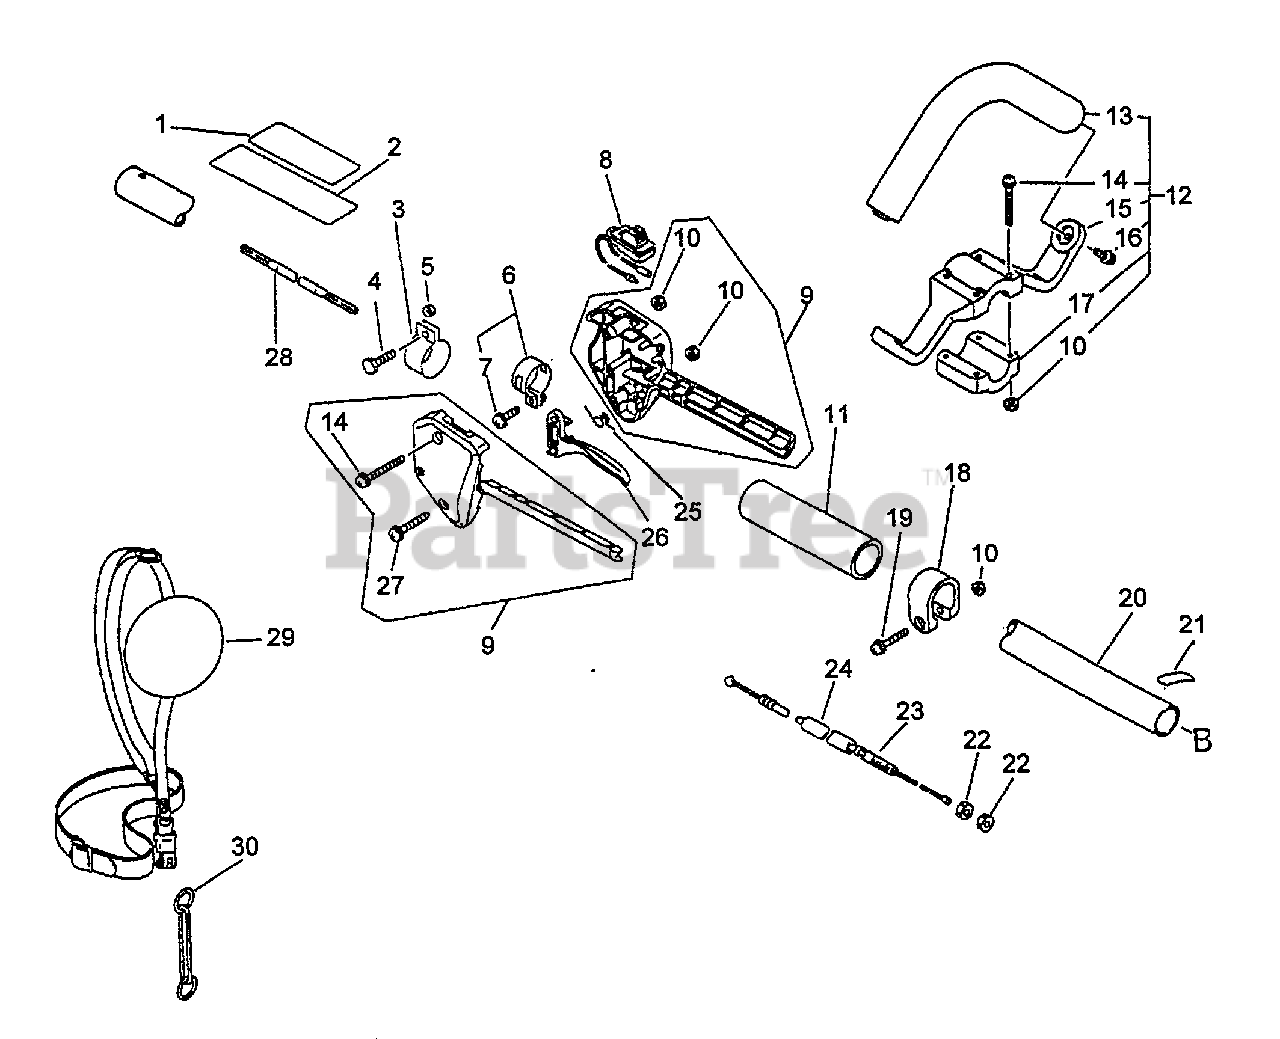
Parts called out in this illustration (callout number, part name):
1	LABEL - CAUTION
2	LABEL - CAUTION
4	BOLT - 5X18
6	MAIN PIPE CLAMP KIT
7	SCREW - 5X12
8	IGNITION SWITCH ASSY
9	CONTROL HANDLE ASSY
11	GRIP, HANDLE
12	HANDLE ASSY
13	HANDLE - FRONT
14	SCREW - 5X35
15	BRACKET, HANDLE - UPPER
16	SCREW - 5X14
17	BRACKET, HANDLE
19	SCREW - 5X30
20	PIPE, MAIN
21	LABEL - ALIGNMENT
23	CABLE, THROTTLE
24	TUBE - VINYL
25	SPRING, TRIGGER
26	TRIGGER, THROTTLE
27	SCREW - 5X25
28	DRIVESHAFT - SOLID
29	SHOULDER STRAP ASSY
